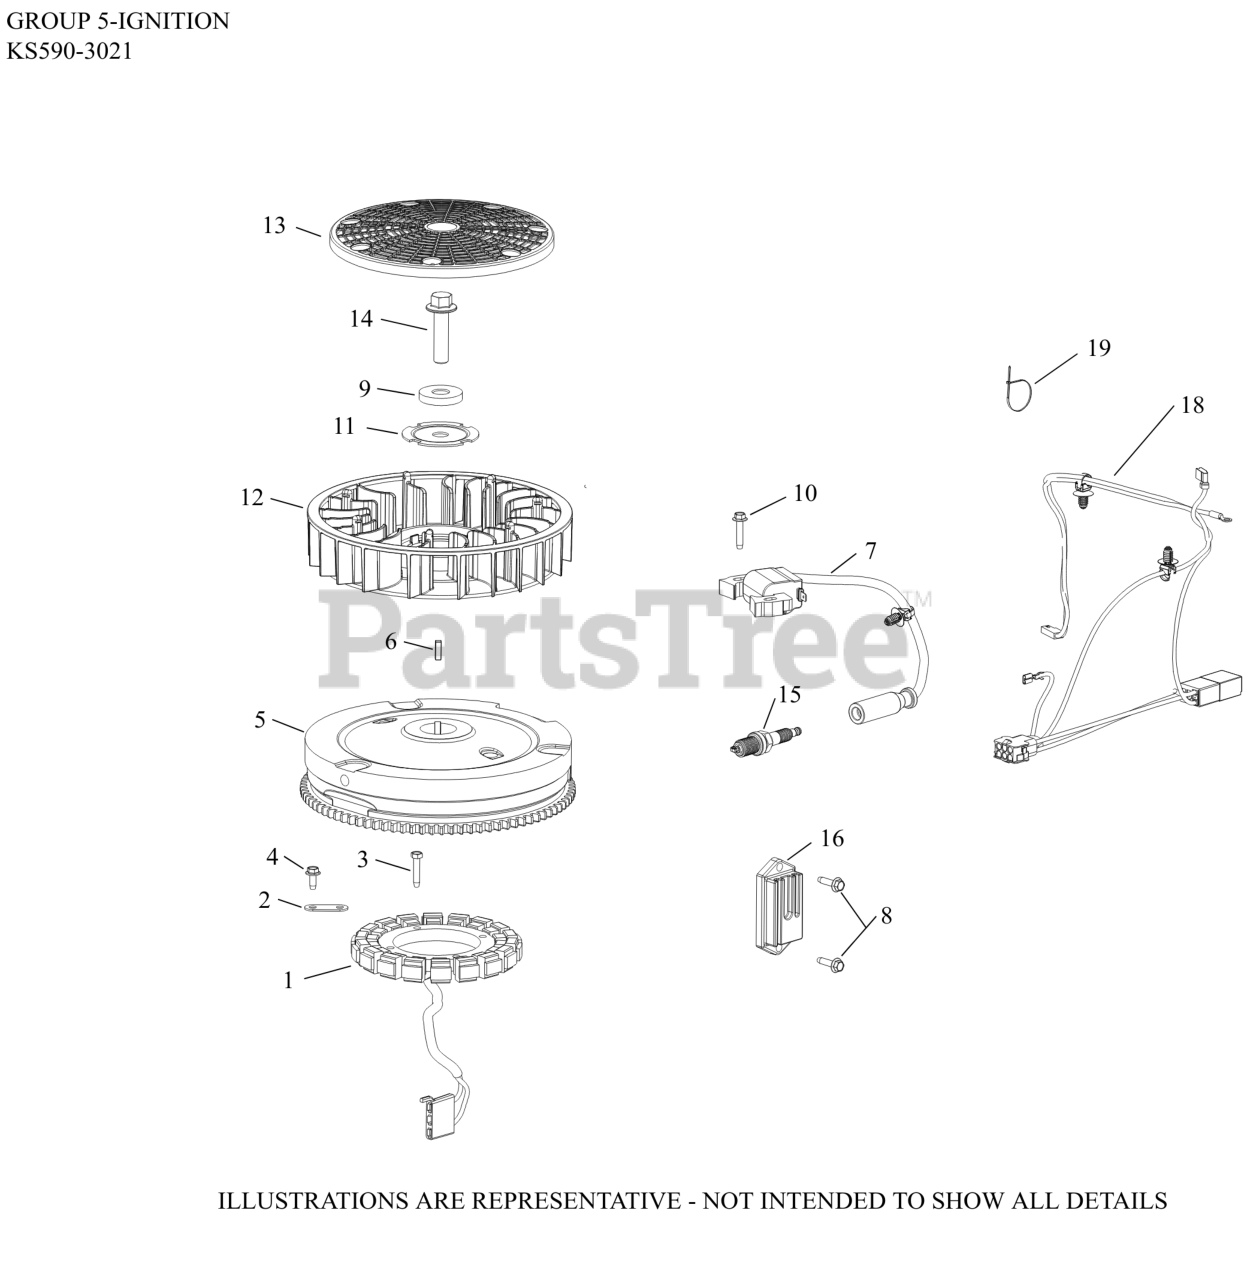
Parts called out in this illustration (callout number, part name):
1	STATOR ASSY, 12A
2	CLIP, STATOR WIRE
3	SCREW, THREAD FORMING
4	SCREW, FLG THD FRM M5X0.8X13
5	FLYWHEEL, ASSY
6	KEY, SQUARE
7	MODULE, INDUCTIVE IGNITION COIL
8	SCREW, THD FRM-USE 25 086 473-S
9	WASHER, FLAT
10	SCREW, THREAD FORMING
11	PLATE, FAN MOUNTING
13	SCREEN, GRASS
14	SCREW, HEX FLANGE
15	PLUG SPARK 12MM RFI
16	REGULATOR/RECTIFIER 12/15A HALF-WAVE STD
18	HARNESS, WIRING SMART CHOKE NON-MTD
